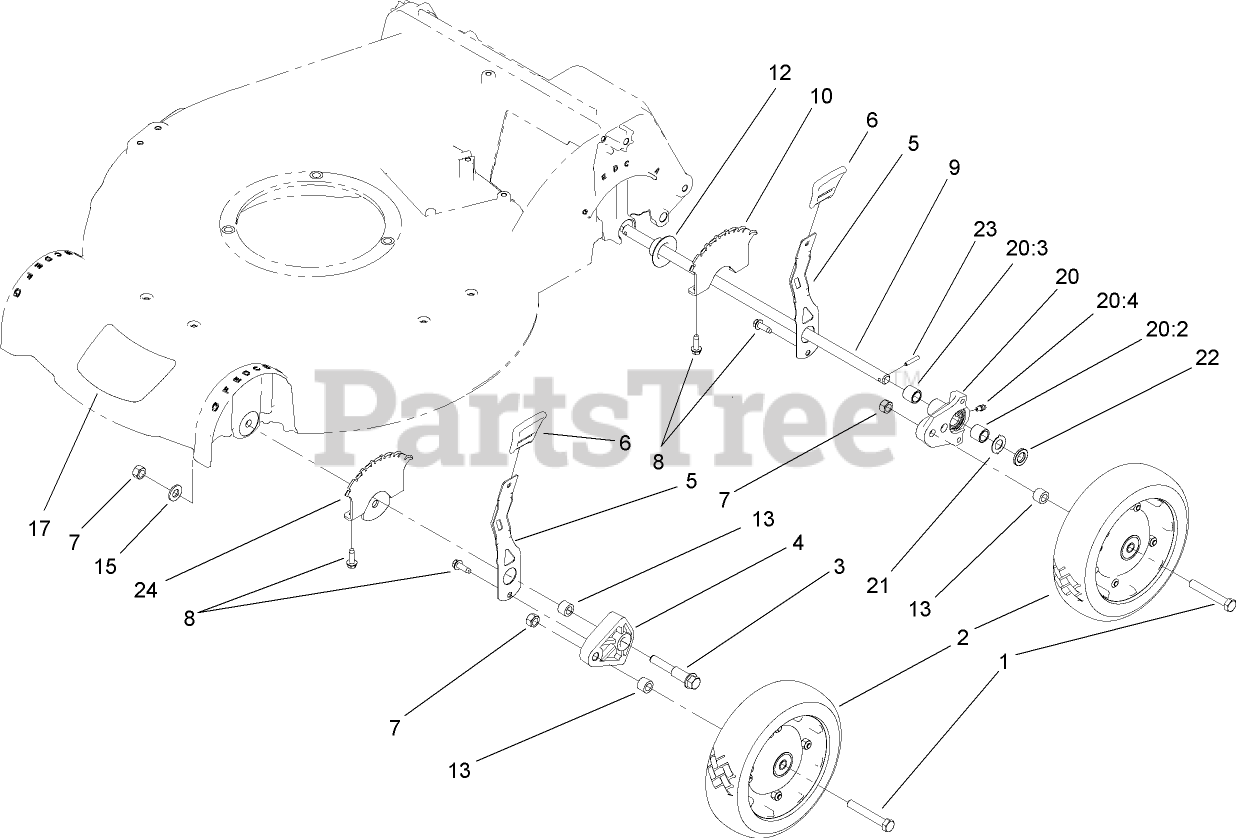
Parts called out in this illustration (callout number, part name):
1	SCREW-HH
4	ARM-PIVOT
5	ARM-SPRING
6	KNOB-HOC
7	LOCKNUT
8	SCREW-HWHTF
9	SHAFT-AXLE, REAR
10	PLATE-HOC
12	CAP-END
13	SPACER-WHEEL
14	DECAL-DANGER
15	WASHER-FLAT
17	DECAL-HOUSING, FRONT
20	PIVOT ARM ASM
20:2	BUSHING
20:3	BUSHING
20:4	FITTING-GREASE
21	WASHER-ARM, PIVOT
22	SPACER-BUSHING
23	PIN-SPIROL
24	BRACKET-SUPPORT
